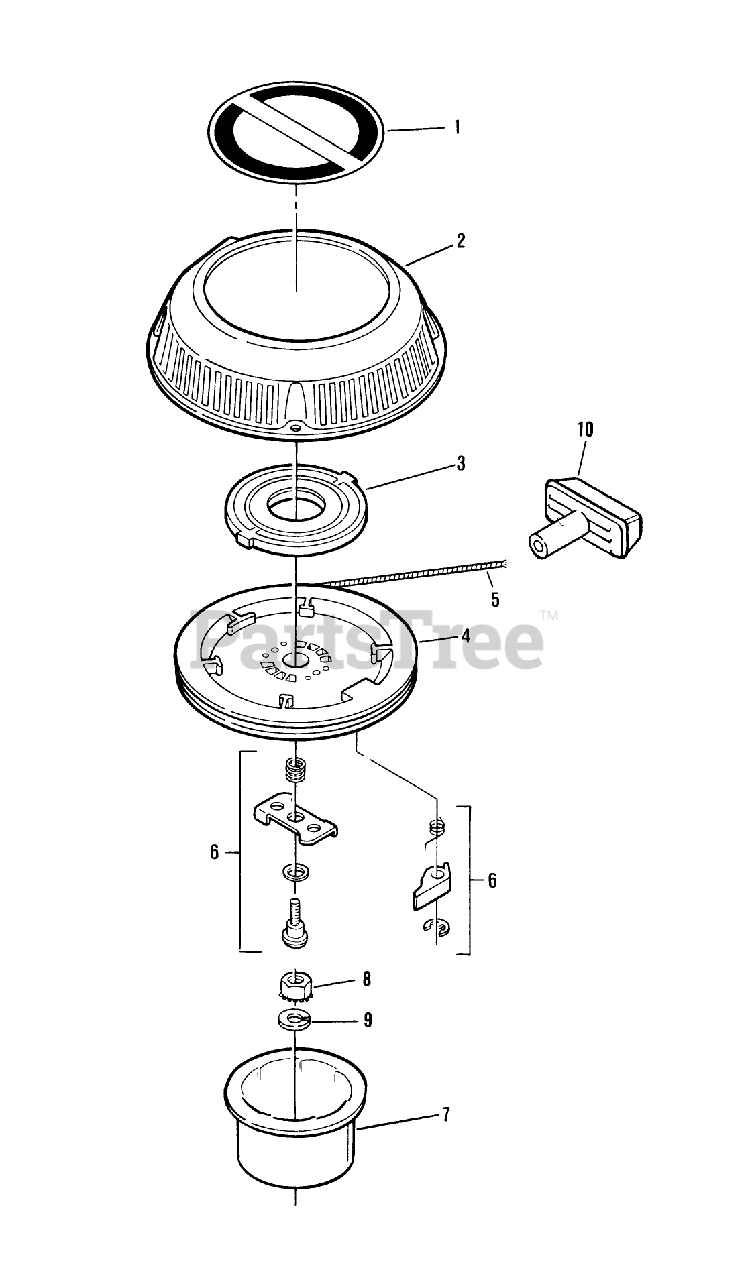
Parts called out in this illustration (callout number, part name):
6	DOG KIT AY.
7	HUB STARTER SM
8	NUT
10	HANDLE START UM&D
